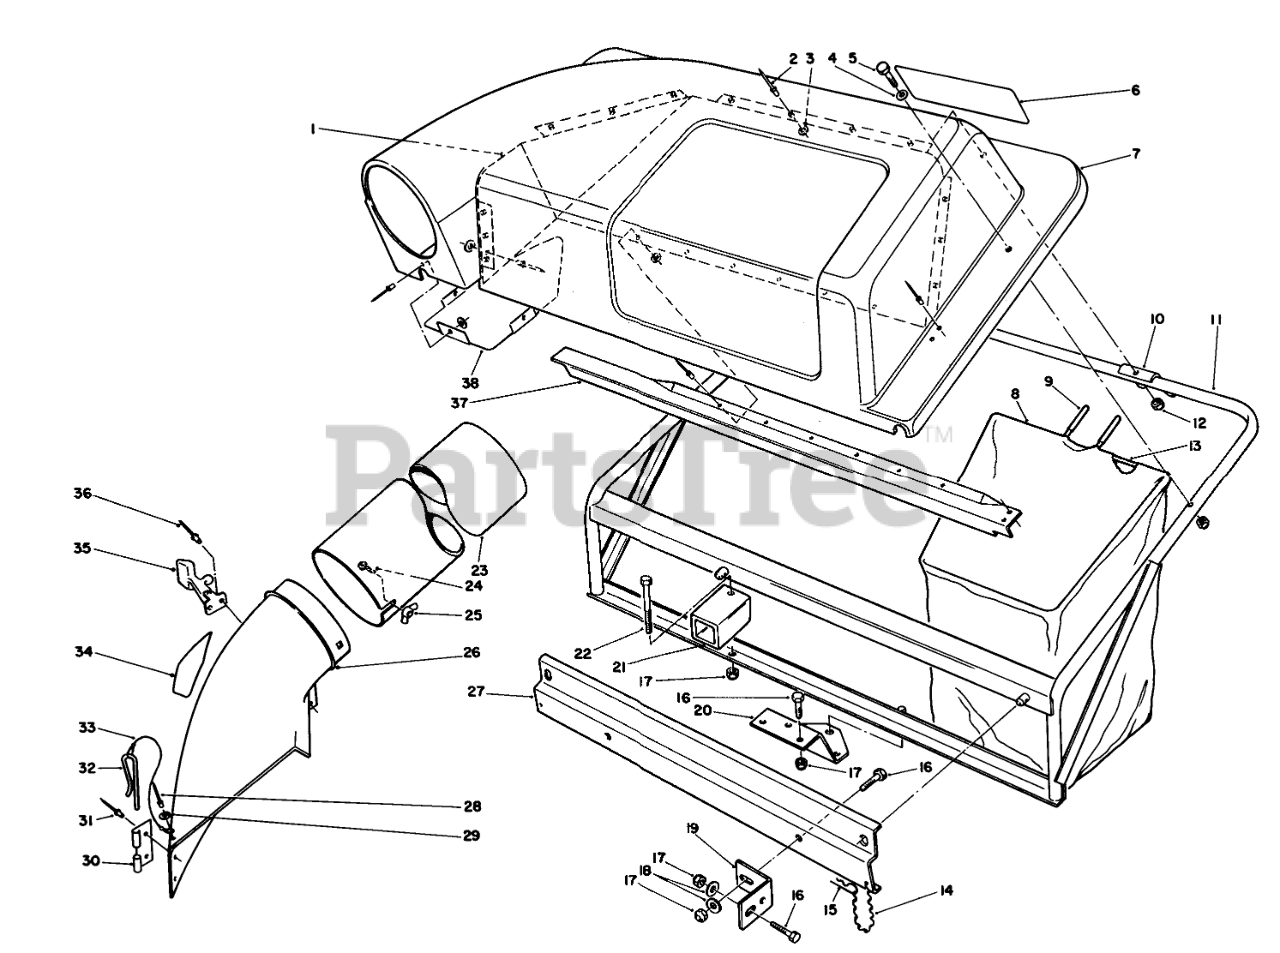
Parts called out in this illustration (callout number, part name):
1	Screen Cover
2	RIVET-POP
3	WASHER-FLAT
4	WASHER-PLAIN
5	SCREW-HH
6	TWIN BAGGER DECAL
7	Cover
9	GRIP-HANDLE, BAG
10	BAG FRAME BRKT
11	Frame
12	NUT-LOCK, CAP
13	Frame-Bag
14	6-LINK CHAIN W/HOOK
15	PIN-HAIR
16	SCREW-HH
17	NUT-LOCK, NI
18	WASHER-PLAIN
19	MTG BRACKET
20	MTG PLATE B
21	FRAME SUPT TUBE B
22	SCREW-HH
23	TUBE(ROUND&LONG)
24	BOLT-CARR
25	NUT-WING SPECL
26	Chute Assembly (Incl. Ref. #28-36)
27	Bracket Frame Support
28	RIVET-BLIND
29	WASHER-PLAIN
30	BRACKET-MOUNTING, CHUTE
31	RIVET-BLIND
32	PIN-LOCKING, CHUTE
33	LANYARD
34	DECAL-DANGER
35	Latch-38"
36	RIVET-POP
37	SCREEN SUPT BRKT B
38	Shield Cover
